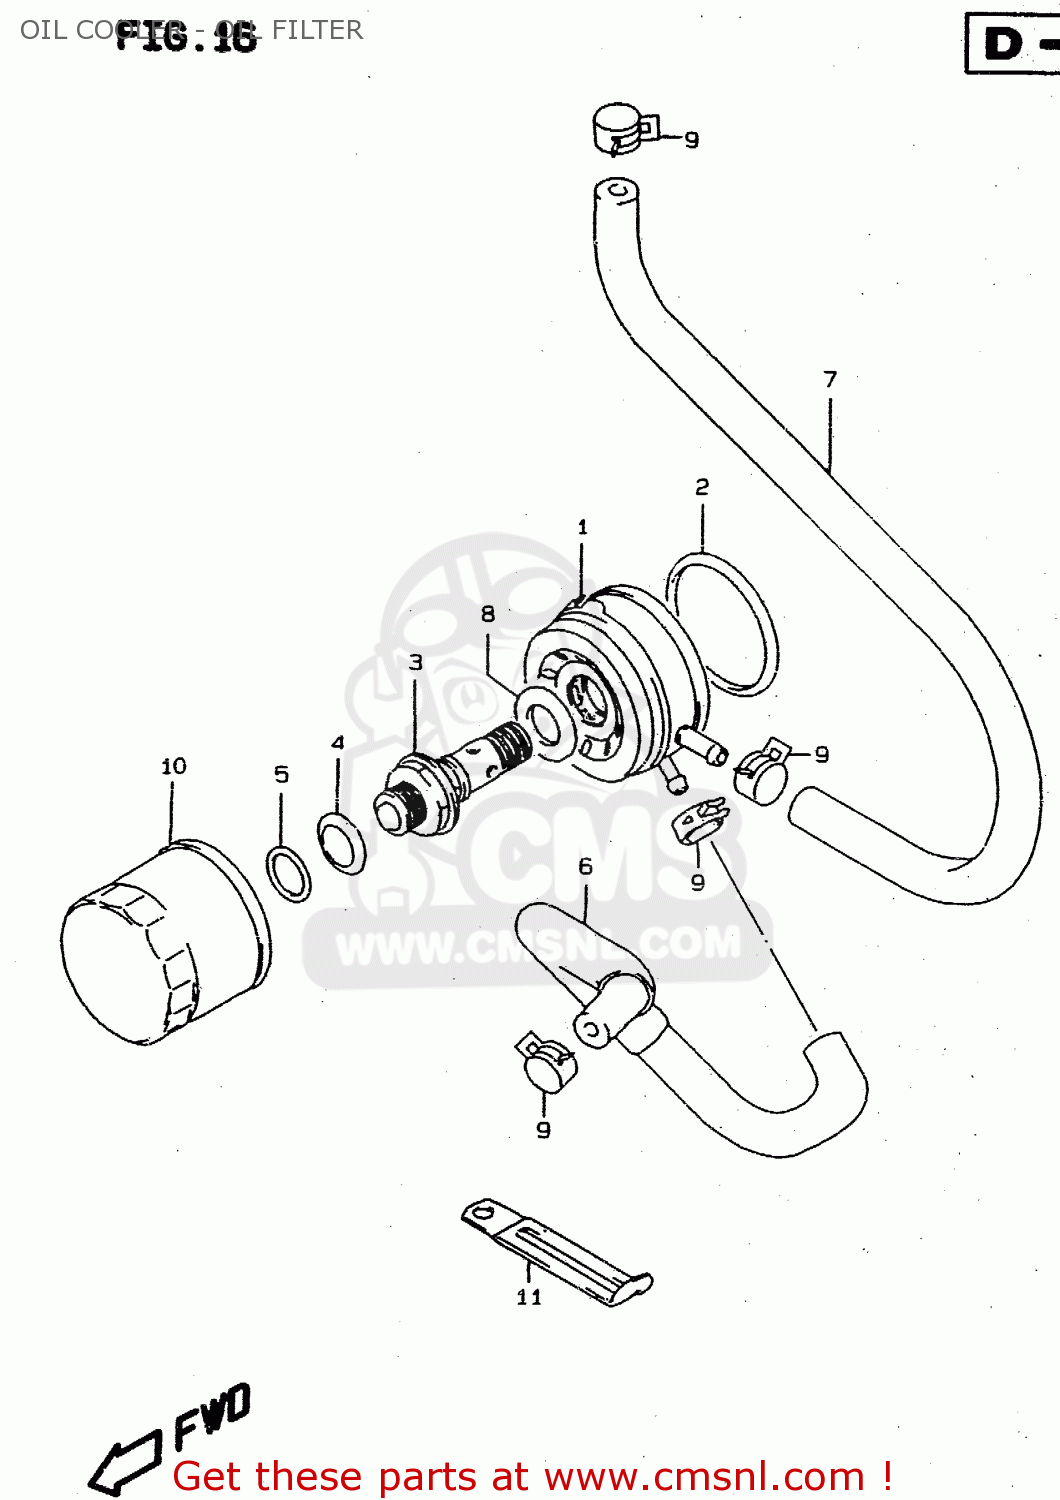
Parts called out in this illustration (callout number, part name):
1	COOLER ASSY,OIL
2	O RING(D:3.1,ID:63.9)
3	BOLT,OIL COOLER UNION
4	WASHER,OIL FILTER WAVE
5	WASHER
6	HOSE,OIL COOLER WATER IN
7	HOSE,OIL COOLER OUTLET
8	SHIM
9	CLIP
10	FILTER ASSEMBLY,ENGINE OIL
11	CLAMP
